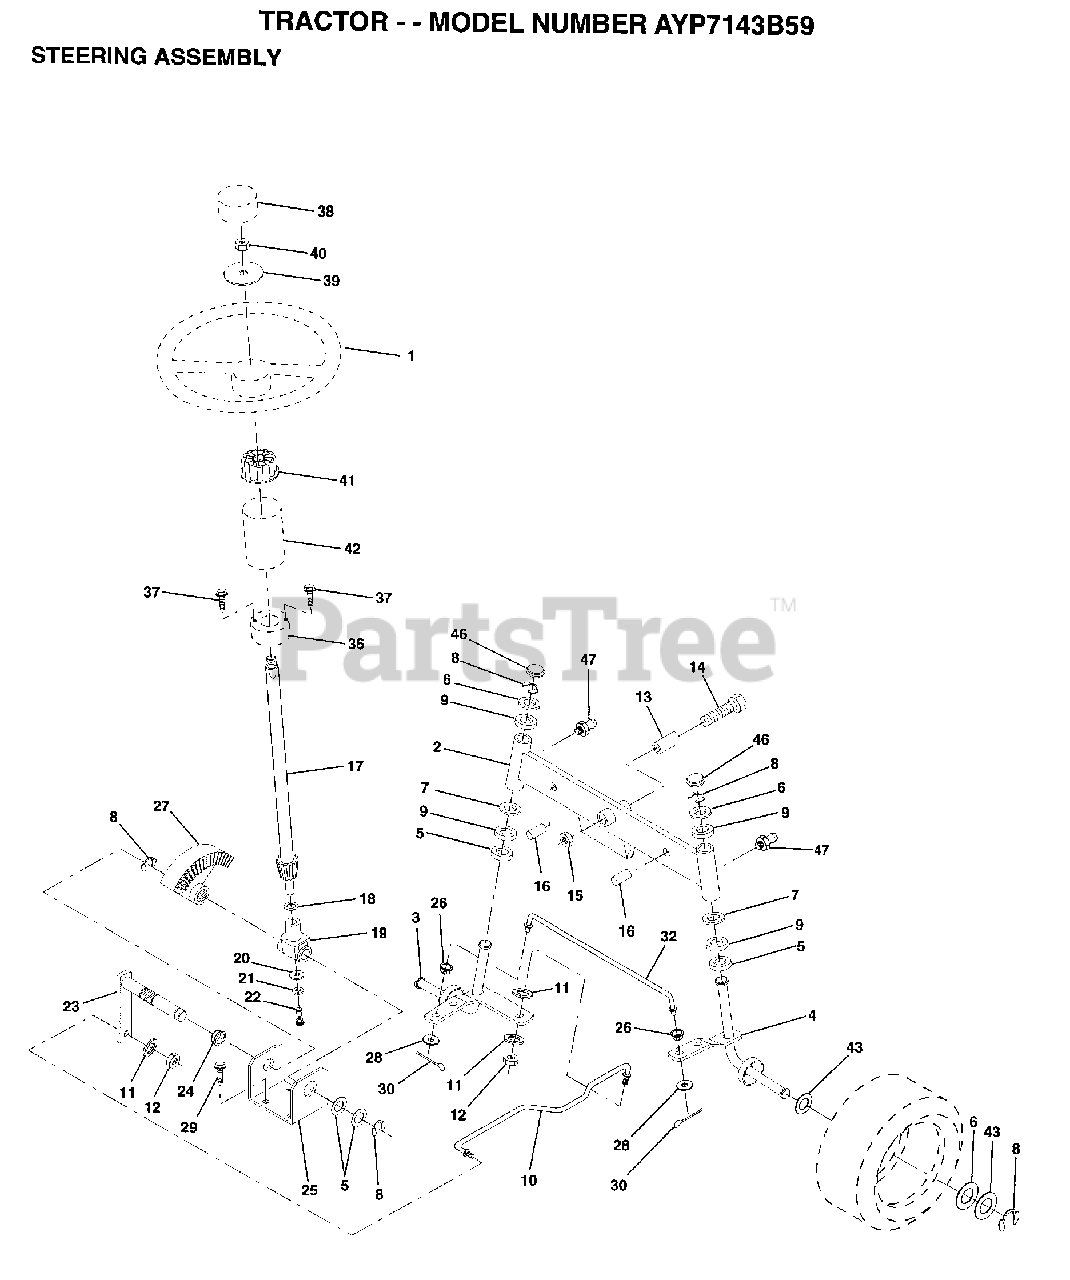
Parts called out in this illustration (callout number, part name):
2	AXLE ASM FRONT
3	SPINDLE LH
4	SPINDLE RH
5	WASHER .T
6	WASHER
7	WASHER
8	RING
9	COL. SRTG. BEAR.
11	LOCKWASHER
13	BEARING
14	BOLT HEX 5/8-11
15	"NUT-LOC,FLANGE LT"
16	AXLE PIN
17	SHAFT ASM
18	THRUST WASHER
19	SUPPORT.SHAFT
21	LOCKWASHER
22	"SCREW,SPECIAL"
24	NYLINER T
25	"BRKT,STEERING"
26	BUSHING.DRAGLINK
27	GEAR SECTOR
28	WASHER
29	SCREW
30	COTTER PIN
32	TIE ROD
38	ST WHL INSERT CAP
39	WASHER T
40	GRIPCO NUT
41	ADAPTER-WHEEL LT
42	"TUBE, STR SHAFT"
43	WASHER
46	CAP
47	ZERK M
